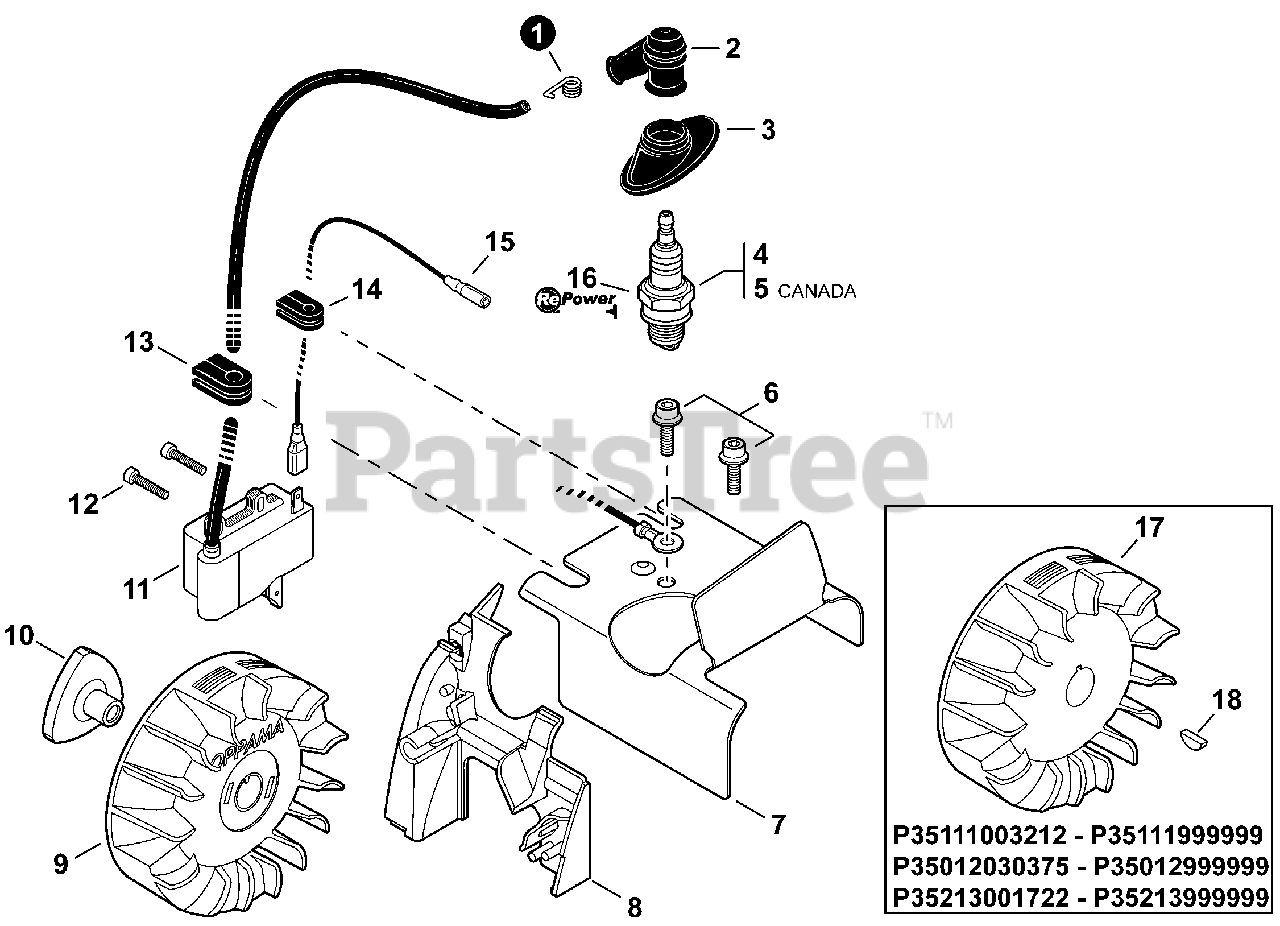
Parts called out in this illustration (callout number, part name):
1	TERMINAL, SPARK PLUG
2	CAP, SPARK PLUG
3	COVER, DUST
4	SPARK PLUG - BPM8Y
5	SPARK PLUG - BPMR8Y
6	BOLT 5×8
7	COVER, CYLINDER
8	COVER, CYLINDER - PLASTIC
9	FLYWHEEL
10	HUB, FAN
11	COIL, IGNITION
12	BOLT 4×20
15	LEAD - IGNITION
16	TUNE-UP KIT - REPOWER
17	FLYWHEEL
18	KEY, WOODRUFF
